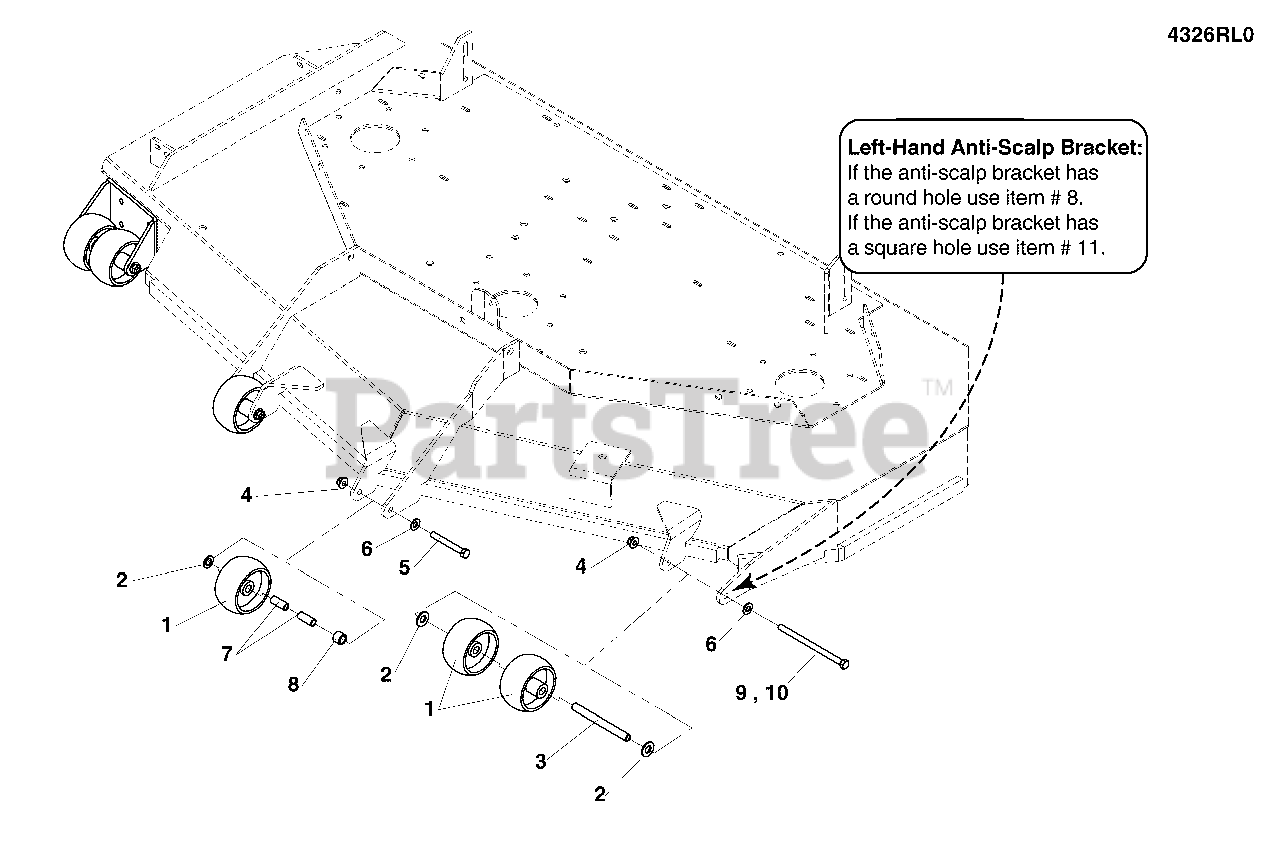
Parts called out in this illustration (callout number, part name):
1	GAUGE WHEEL
2	WASHER, 1/2" GD9 YZ
3	SPACER, .38 X .50 X 5.06
4	NUT, 3/8-16 HEX SIDE LOCK
5	BOLT, 3/8-16 X 3" GD5
6	WASHER, 3/8 SAE
7	SPACER, .38 X .50 X 1.25
8	SPACER, .51 X .75 X .56
9	BOLT, 3/8-16 X 6" GR5 YZ
10	BOLT, CARRIAGE, 3/8-16X6, GD5, CZ
